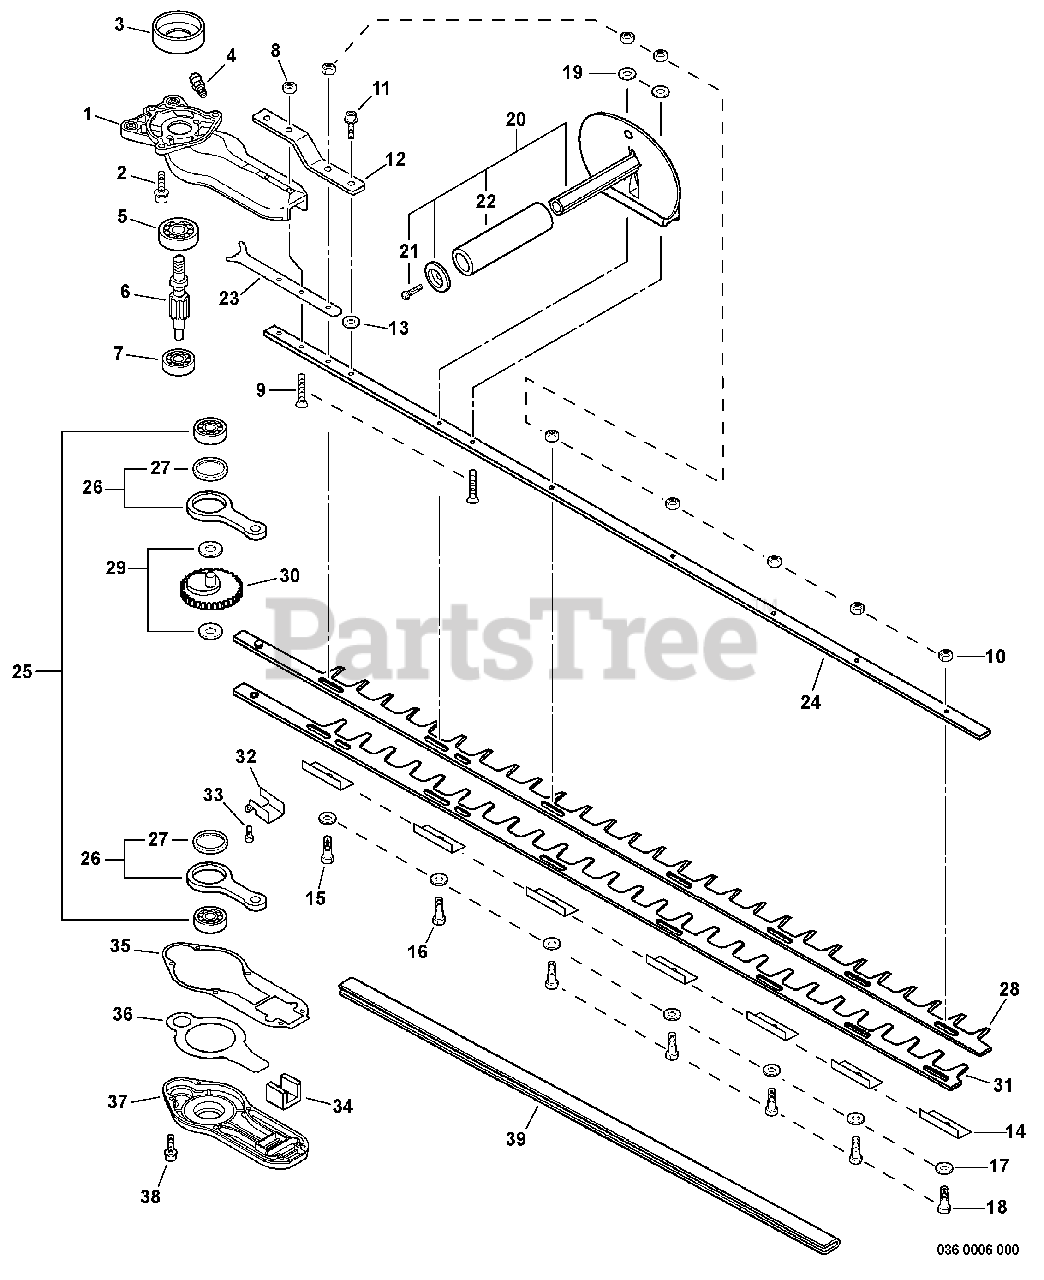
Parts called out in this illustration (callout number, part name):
1	CASE, GEAR - UPPER
2	BOLT 6×18
3	DRUM, CLUTCH
4	FITTING, GREASE
5	BEARING, BALL 6200
6	GEAR, SPUR
7	BEARING, BALL 608ZZ
8	NUT, FLANGE M6
9	BOLT 6×30
11	SCREW - 6×12
12	BRACKET, BLADE
14	GUIDE, BLADE
15	BOLT 6×35
16	BOLT 6×40
18	BOLT 6×22
19	WASHER 6.5×13×1
20	FRONT HANDLE ASSY
21	SCREW 5×14
22	GRIP, HANDLE
23	PLATE, EYE
24	SUPPORT, BLADE 40"
25	BEARING, BALL 6200
26	ROD, CONNECTING
27	BEARING, NEEDLE 30
28	BLADE, UPPER 40"
29	WASHER, THRUST 10
30	GEAR, SPUR
31	BLADE, LOWER 40"
32	GUIDE, BLADE
33	BOLT 4×16
35	GASKET, GEAR CASE
36	PLATE, GEAR CASE
37	COVER, GEAR CASE
38	BOLT 4×16
39	SCABBARD
